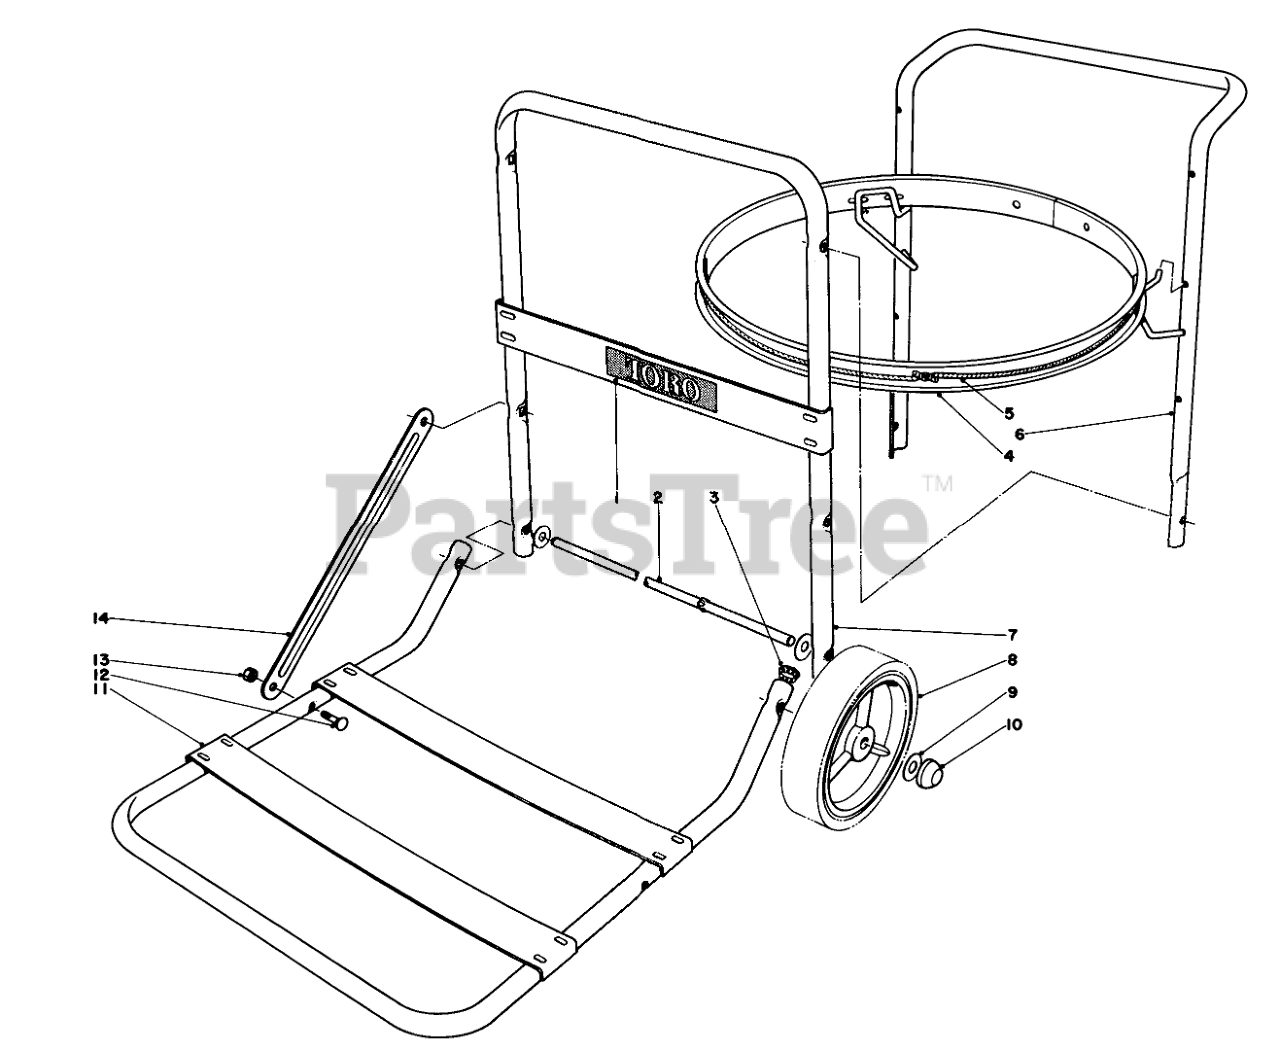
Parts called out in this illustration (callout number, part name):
1	Decal
3	Plug Button
5	Retainer Cord
6	Upper Handle
7	Lower Handle
8	Wheel
9	WASHER-FLAT
10	Hub Cap
12	SCREW-CARR
13	NUT-HEX
14	Brace
